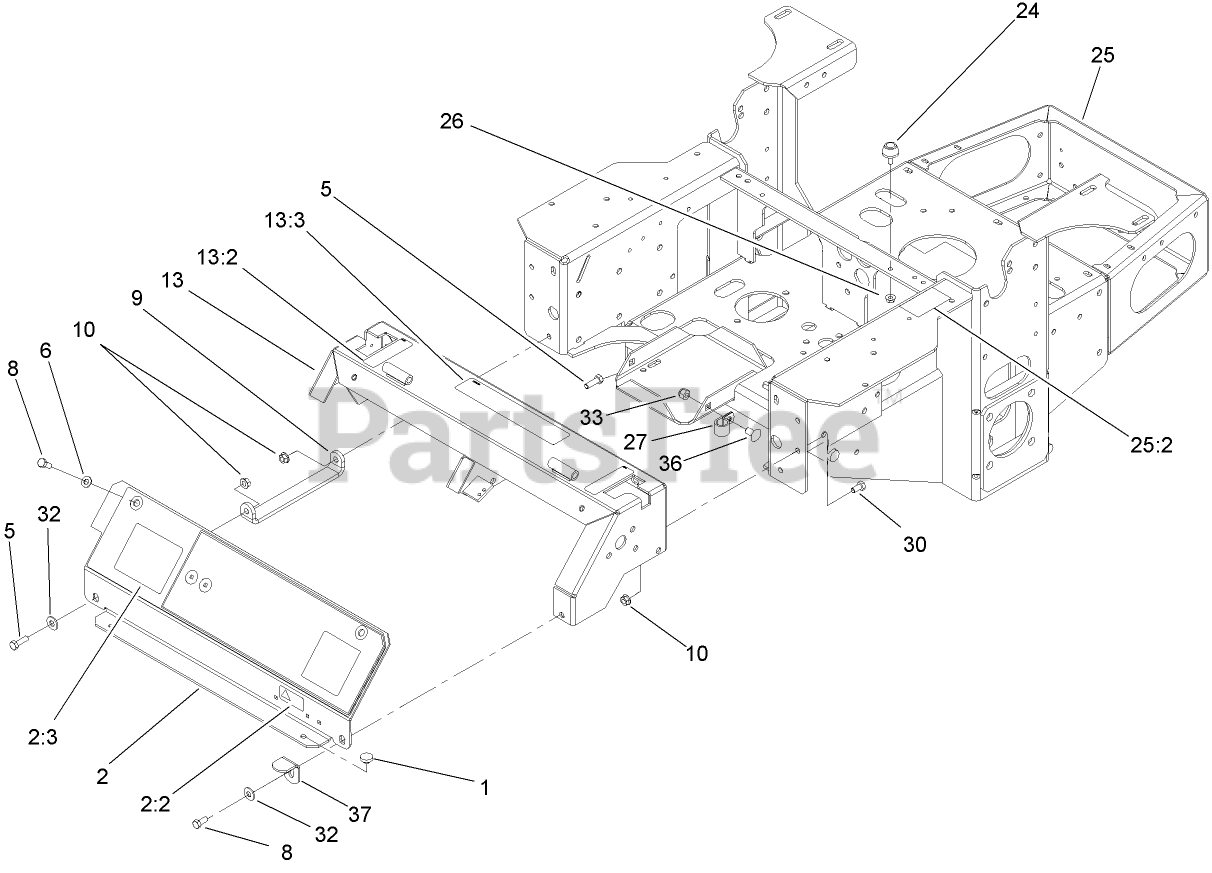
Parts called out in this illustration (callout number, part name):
1	BUMPER
2:2	DECAL-PROTECTION, EAR
2:3	DECAL-PANEL, COVER
5	SCREW-HH
6	WASHER-PLAIN
8	SCREW-HH
9	BRACKET-PANEL, INSTRUMENT
10	NUT-HF
13	CONSOLE ASM
13:2	DECAL-CONTROL, MOTION
13:3	DECAL-BATTERY
24	BUMPER-RUBBER
25	MAIN FRAME ASM
25:2	Decal-Release, Drive
26	NUT-HF
27	CLIP-LOOM
30	SCREW-HH
32	WASHER-FLAT
33	NUT-LOCK, NI
36	SCREW-CARR
37	STOP-COVER
